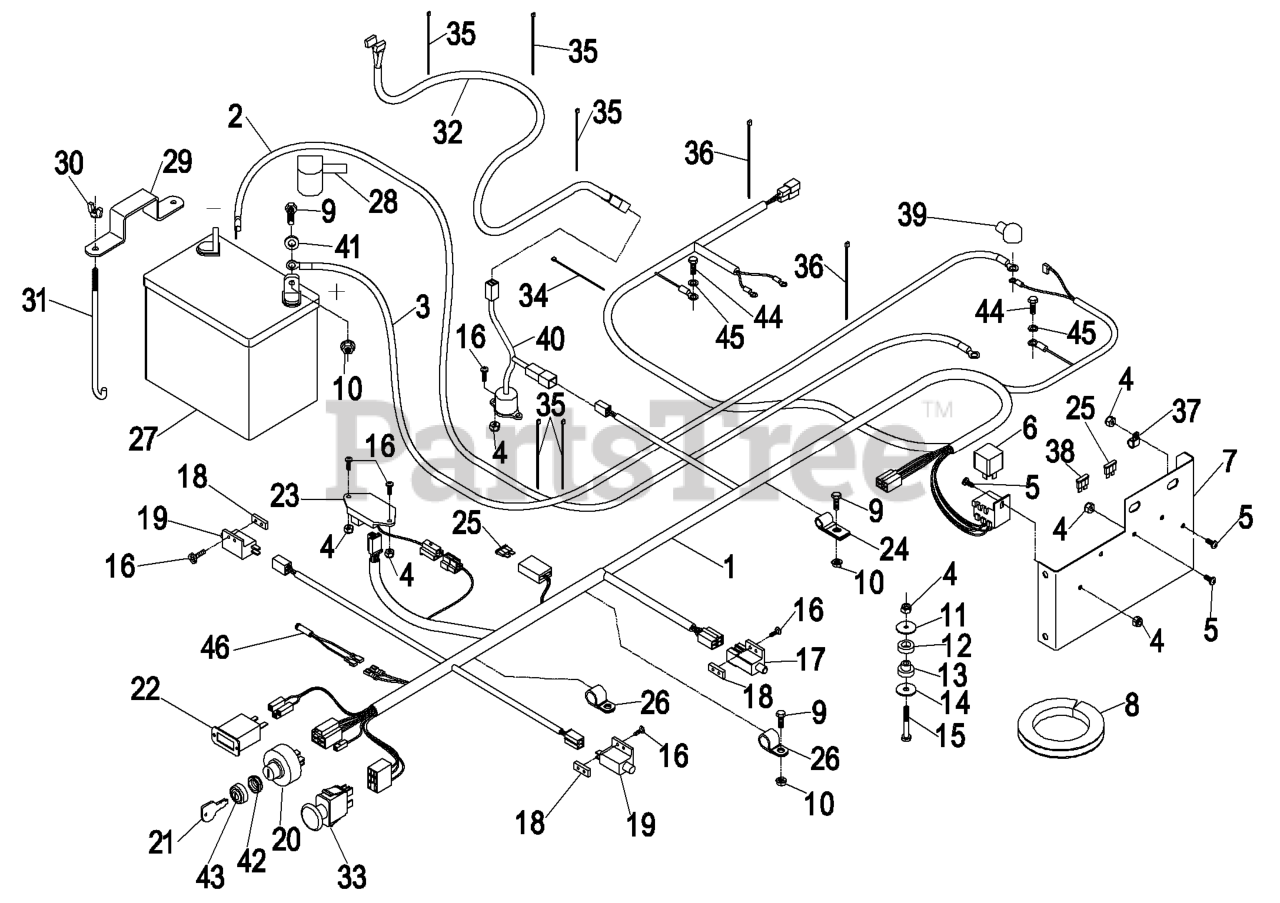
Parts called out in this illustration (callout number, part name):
2	WIRE-GROUND
4	NUT-LOCK, NI
8	TRIMLOCK
9	SCREW-HH
12	RINGMOUNT-VIBRATION
13	MOUNT-BUSHING, VIBRATION
16	SCREW-PPH
18	PLATE-TAPPED
19	SWITCH-OPEN, NORMALLY
21	KEYS-IGNITION (SPARE PAIR
22	METER-HOUR
23	MODULE-DELAY, SEAT
24	CLIP-LOOM
25	FUSE-BLADE TYPE, 20 AMP
26	CLIP-LOOM
30	WINGNUT
31	BOLT-HOLDDOWN
34	TIE-CABLE
35	TIE-PLASTIC
36	TIE-PLASTIC
37	CLIP-LOOM
39	INSULATOR-SOLENOID
41	WASHER-FLAT
42	NUT-SWITCH, IGNITION
43	SEAL-SWITCH, IGNITION
44	SCREW-HH
45	WASHER-PLAIN
46	INDICATOR-LED, RED
